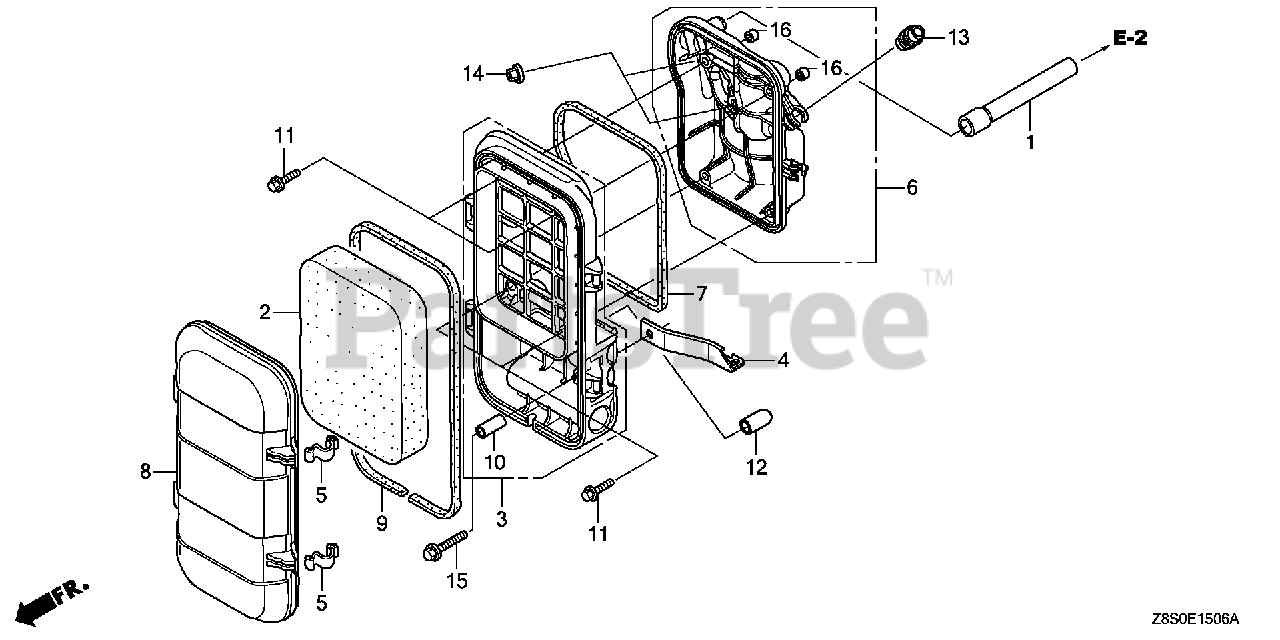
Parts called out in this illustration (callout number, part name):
1	TUBE, BREATHER
2	ELEMENT, AIR CLEANER
3	HOUSING, AIR CLEANER
4	STAY, AIR CLEANER
5	SPRING, AIR CLEANER HOUSING LID
6	BASE, AIR CLEANER
7	SEAL, AIR CLEANER HOUSING
8	COVER, AIR CLEANER
9	SEAL, AIR CLEANER COVER
10	COLLAR, AIR CLEANER
11	BOLT, FLANGE (5X18)
12	CAP, SEALING
13	RUBBER, FUEL (9X15X20)
14	NUT, FLANGE (6MM)
15	BOLT, FLANGE (6X32)
16	COLLAR, AIR CLEANER
